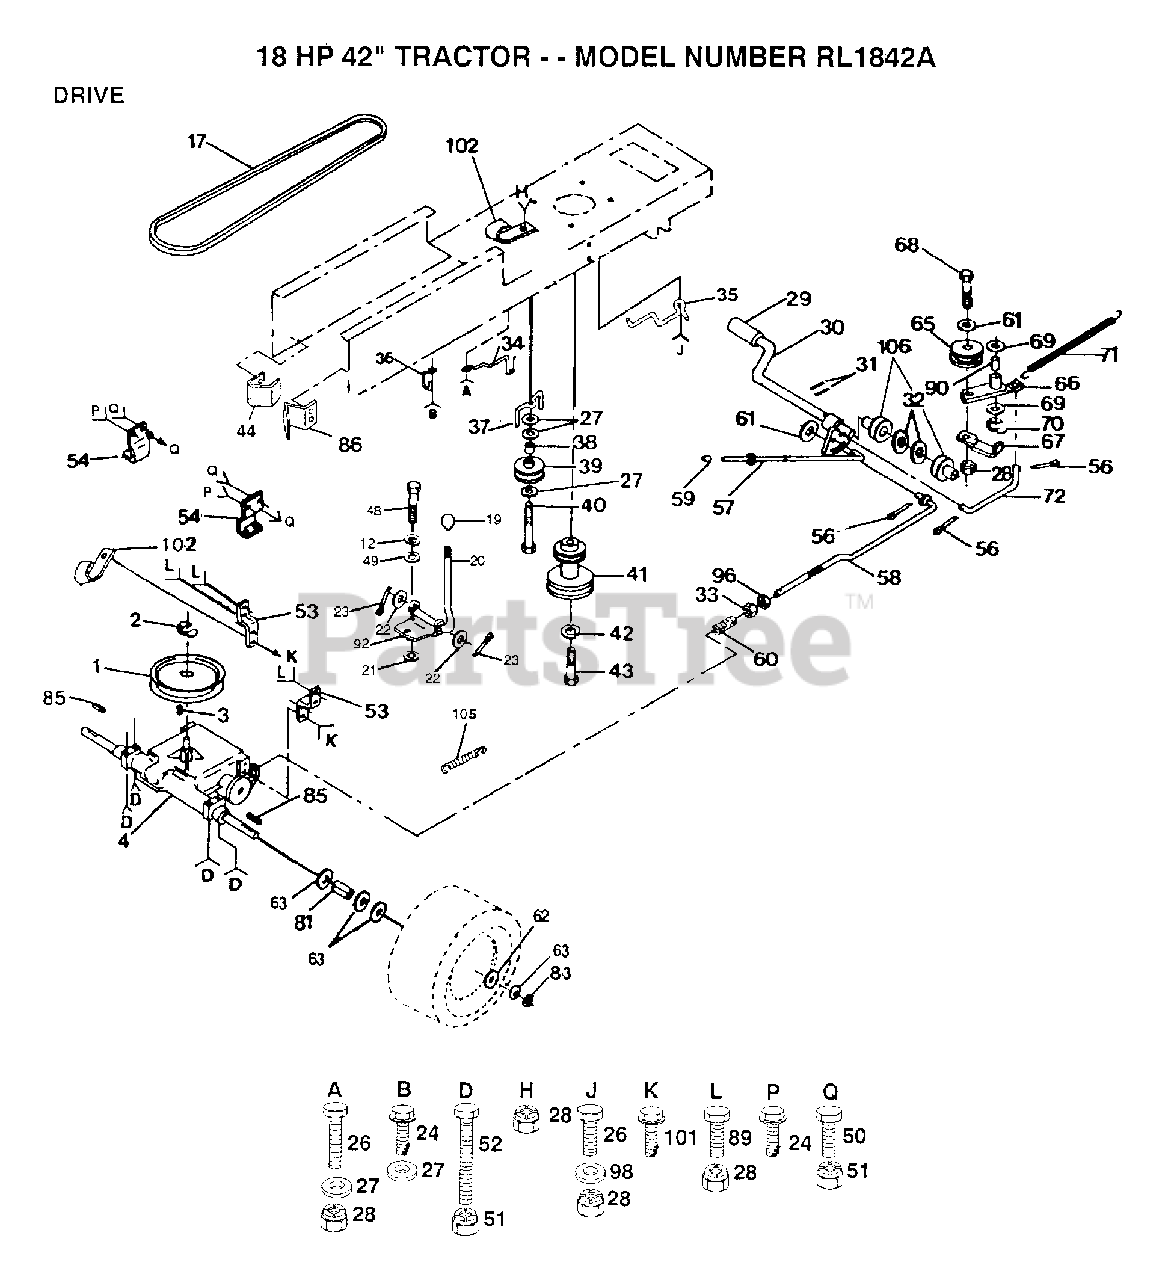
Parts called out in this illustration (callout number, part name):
1	PULLEY TRANS
12	LOCKWASHER
17	BELT.V.GDRIVE.95
19	KNOB T (1/2-HOLE)
20	SHIFT ROD
21	WASH-SHFT PLT LT
22	WASHER
23	PIN COTTER 1/8
24	SCREW
26	BOLT
27	WASHER
29	PEDAL COVER T
32	WASHER LT
33	NUT
34	KEEPER.BELT.ENG.L
35	KEEPER BELT ENG
37	BELT KEEPER LT
38	SPACER T
39	PULLEY.IDLER.FLAT
40	BOLT
42	LOCKWASHER
43	BOLT
44	"KEEPER,BELT LH T"
49	WASHER LT
50	BOLT
52	BOLT
53	STRAP TORQUE
54	TRANSAXLE MTG BKT
56	COTTER PIN
57	BRAKE PARK ROD
58	BRAKE ROD
59	PLUNGER CAP T
60	SPRING ROD LT
61	WASHER
62	WASHER
63	WASHER
66	ARM IDLER
67	RETAIN BELT
69	WASHER LT
70	KLIP RING
71	"SPRING, RETURN LT"
72	"CHAIN,24 PTCH LT"
81	SPACER LT
83	E-RING LT
85	SQUARE KEY
86	"KEEPER,BELT RH T"
90	"LY, BEARING"
96	NUT
98	WASHER
101	SCREW
102	CLIP T
106	NYLON BEARING
